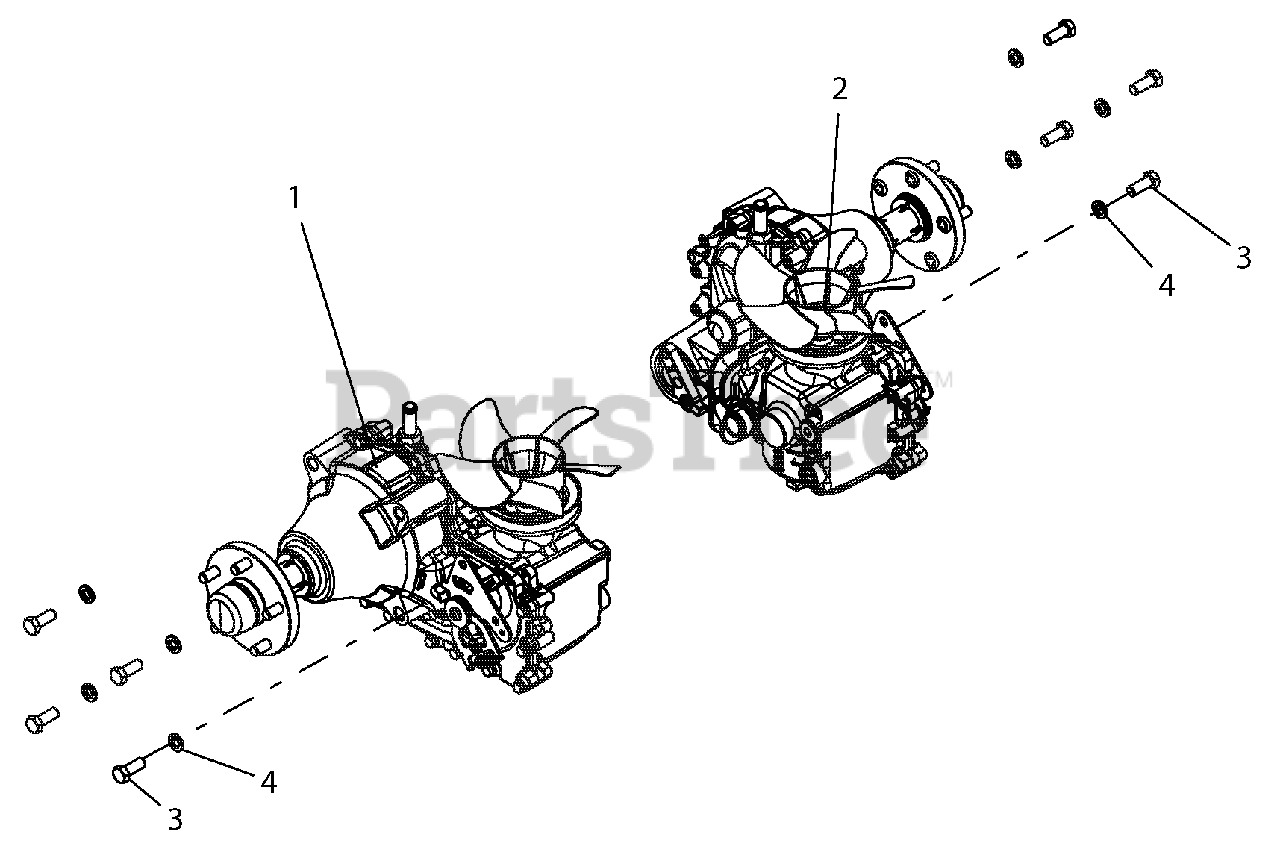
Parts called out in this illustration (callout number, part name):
1	TRANS, R.H. HG ZT-5400
2	TRANS, LH HG ZT-5400
3	BLT-HEX .50-13X1.25 GR5 YWZC
4	WSHR-LK .50X.125 REG YWZC
